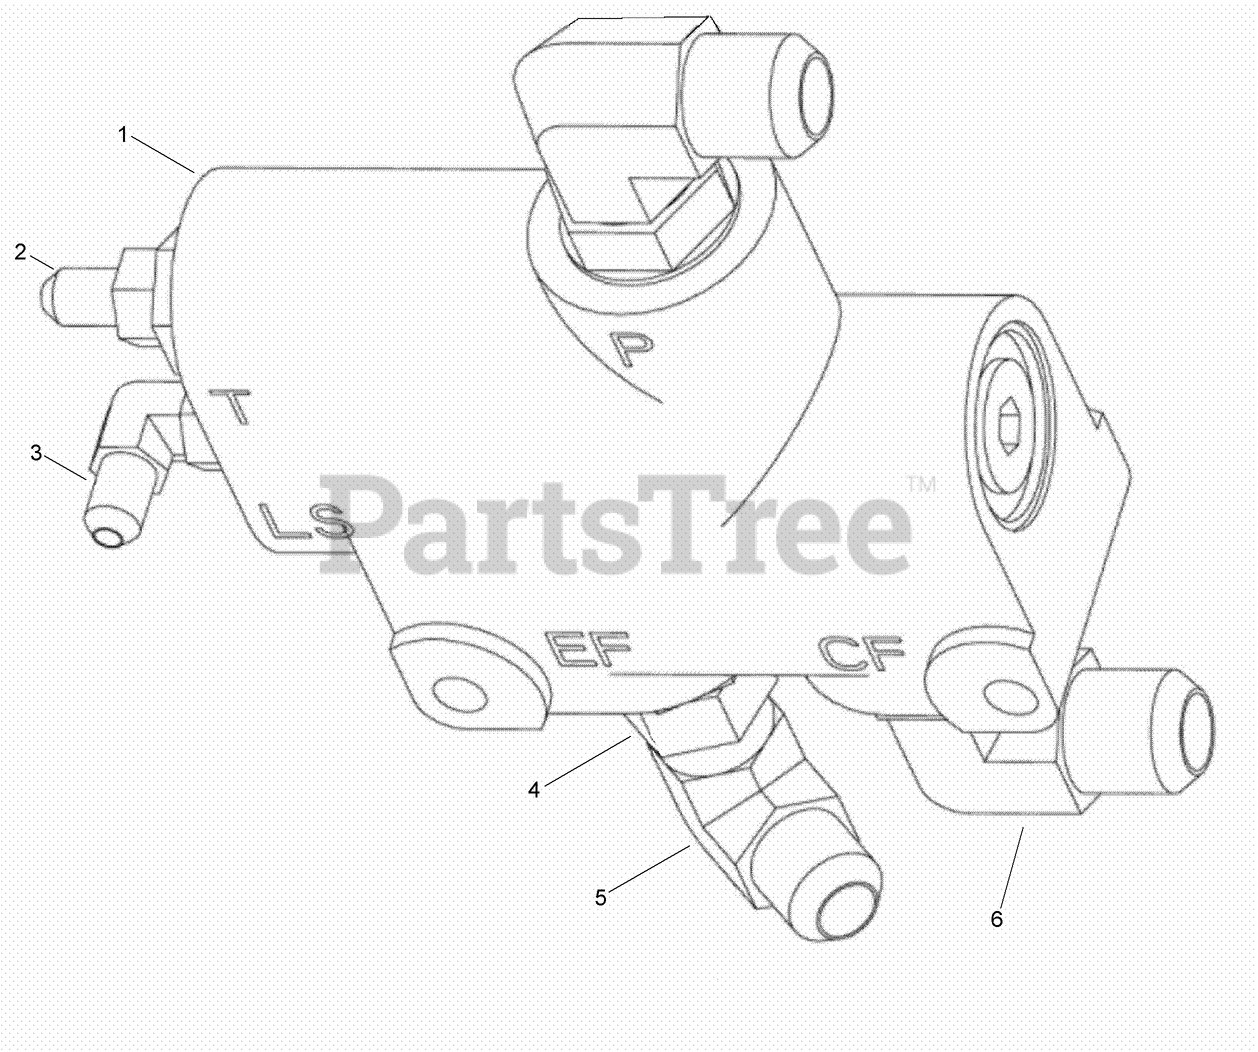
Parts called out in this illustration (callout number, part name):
1	HYD PRIORITY FLOW DIVIDER ASM
2	CONNECTOR-Str Thd 1/4, 37FL-ORB 1/4
3	ELBOW-90 Adj 37FL 1/4 Tube
4	CONNECTOR-Str Thd 1/2, 37FL-ORB 1/2
5	ELBOW-90 Swivel 37FL 1/2 Tube
6	ELBOW-90 Adj 37FL 5/8 Tube
